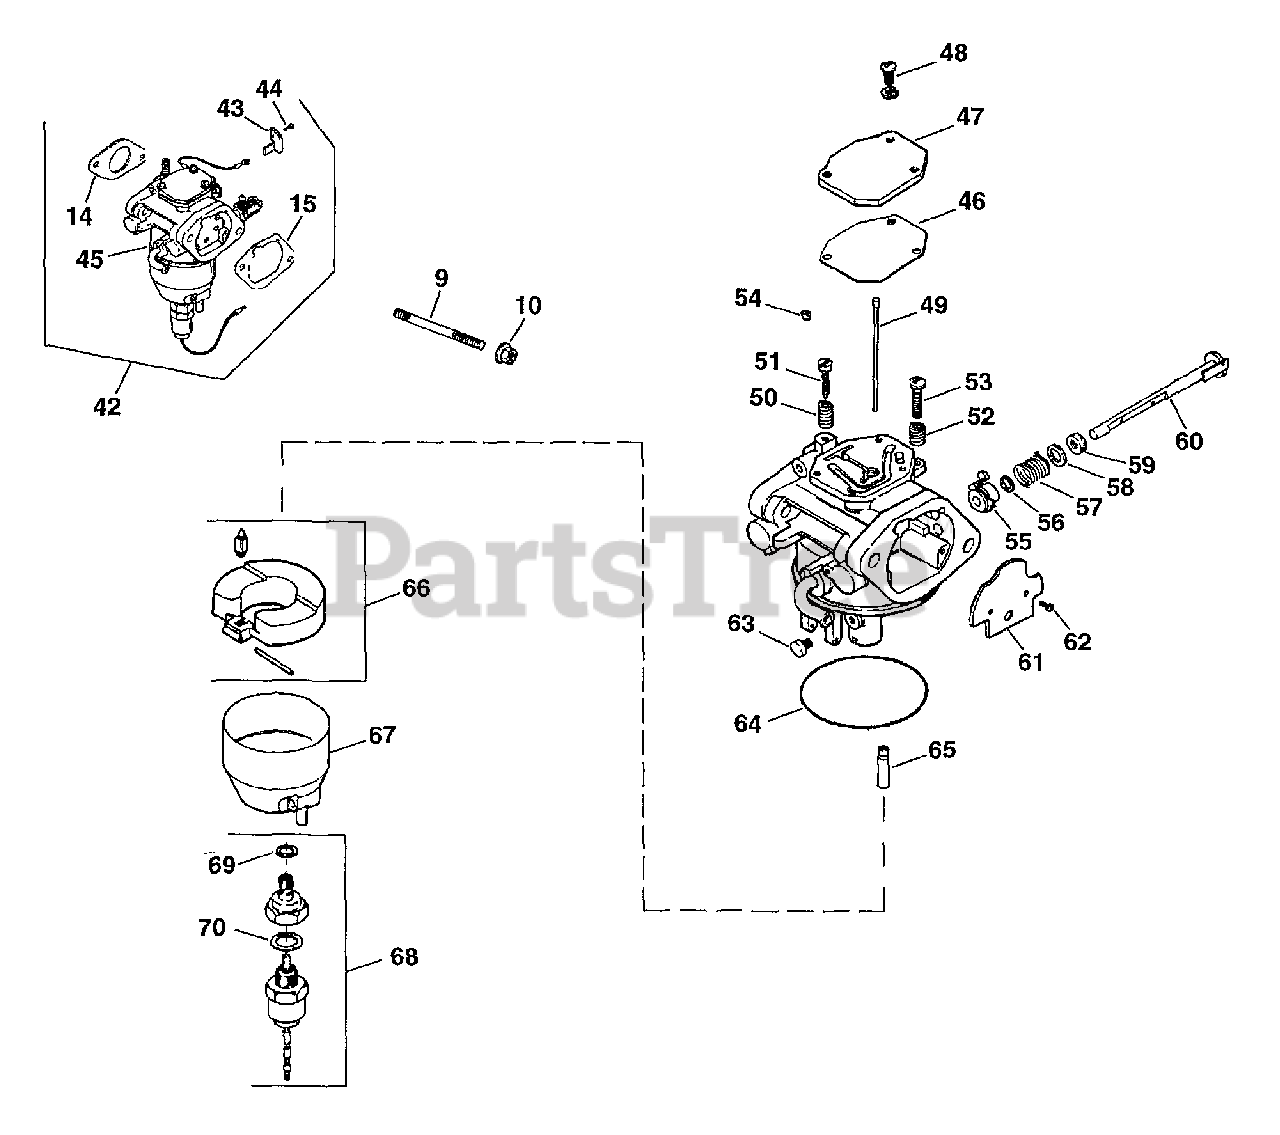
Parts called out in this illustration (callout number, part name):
9	Stud, M6x1.0x95
10	NUT - USE M-641060
14	GASKET, CARBURETOR
15	GASKET, AIR CLEANER BASE
42	CARBURETOR KIT-USE 24 853 41-S
43	BRACKET, THROTTLE STOP
44	Screw, phillips hd. M2x0.45x6
